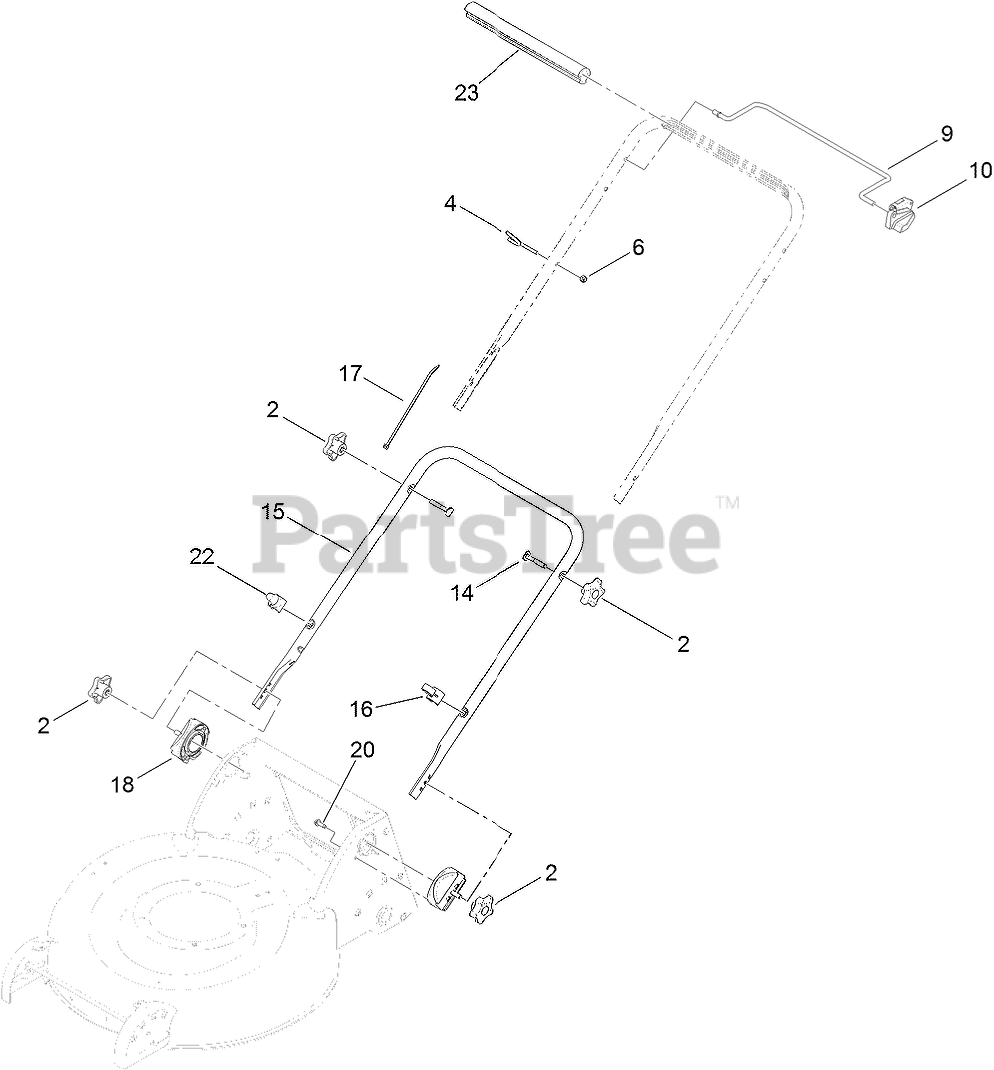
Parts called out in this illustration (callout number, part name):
2	KNOB-HANDLE
4	GUIDE-ROPE
6	NUT-LOCK, NI
9	Bail-Control
10	Stop-Pivot
14	SCREW-HANDLE
15	HANDLE-LOWER
16	GUIDE-CABLE
17	TIE-CABLE
18	HANDLE MOUNT ASM
20	SCREW-HWHTF
22	GUIDE-ROPE, LOWER
23	GRIP-HANDLE, COMFORT
